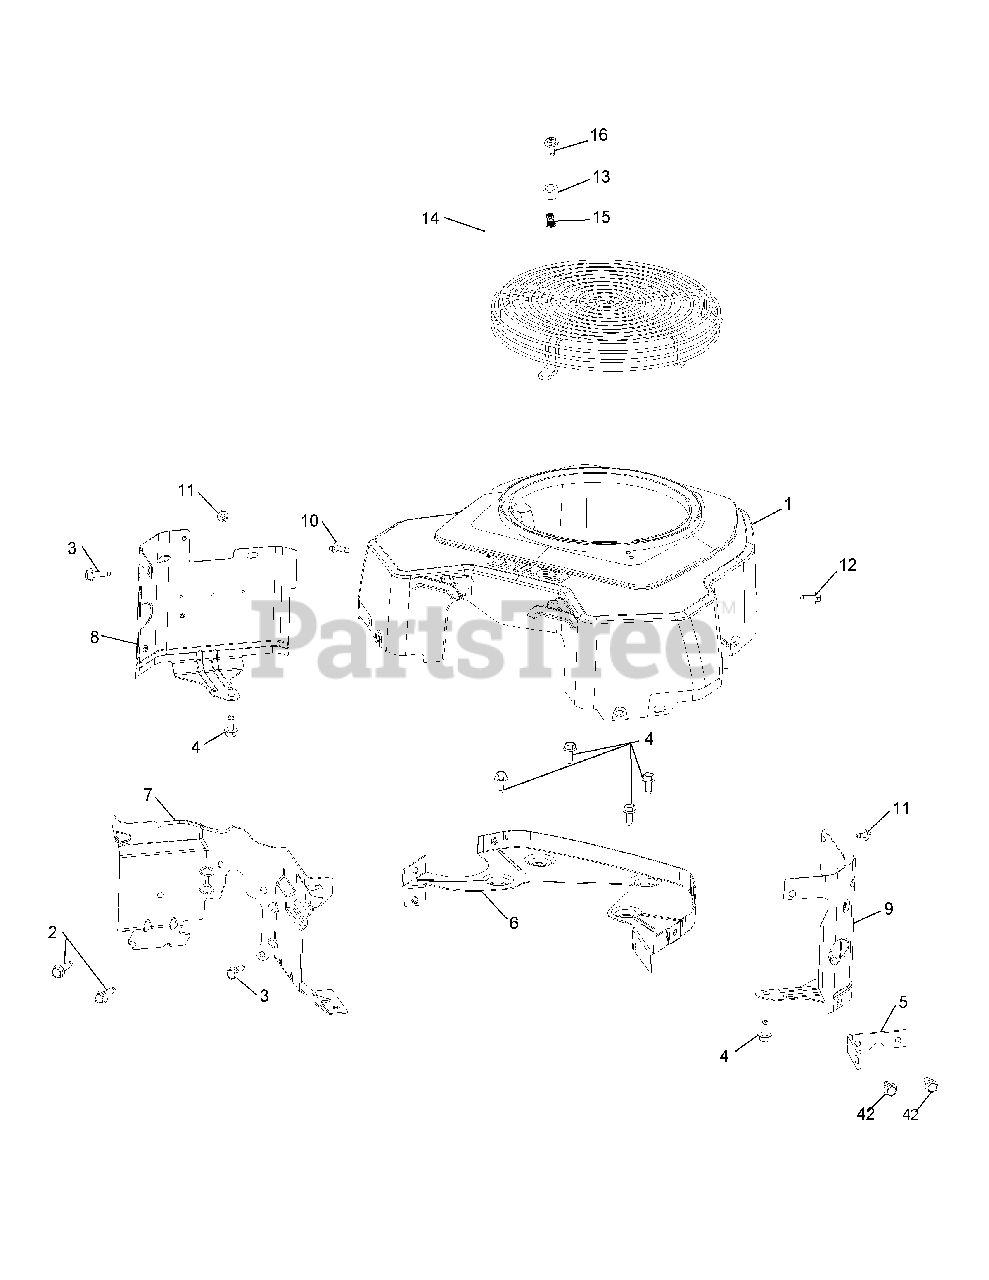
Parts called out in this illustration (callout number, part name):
1	Blower Housing
2	Thread Forming Screw
3	Thread Forming Screw
4	Thread Forming Screw
6	Backing Plate Kit
8	Cylinder Barrel Kit, #1 Side
9	Cylinder Baffle Kit, #2 Side
10	Thread Forming Screw
11	Thread Forming Screw
12	Thread Forming Screw
15	Threaded Insert
